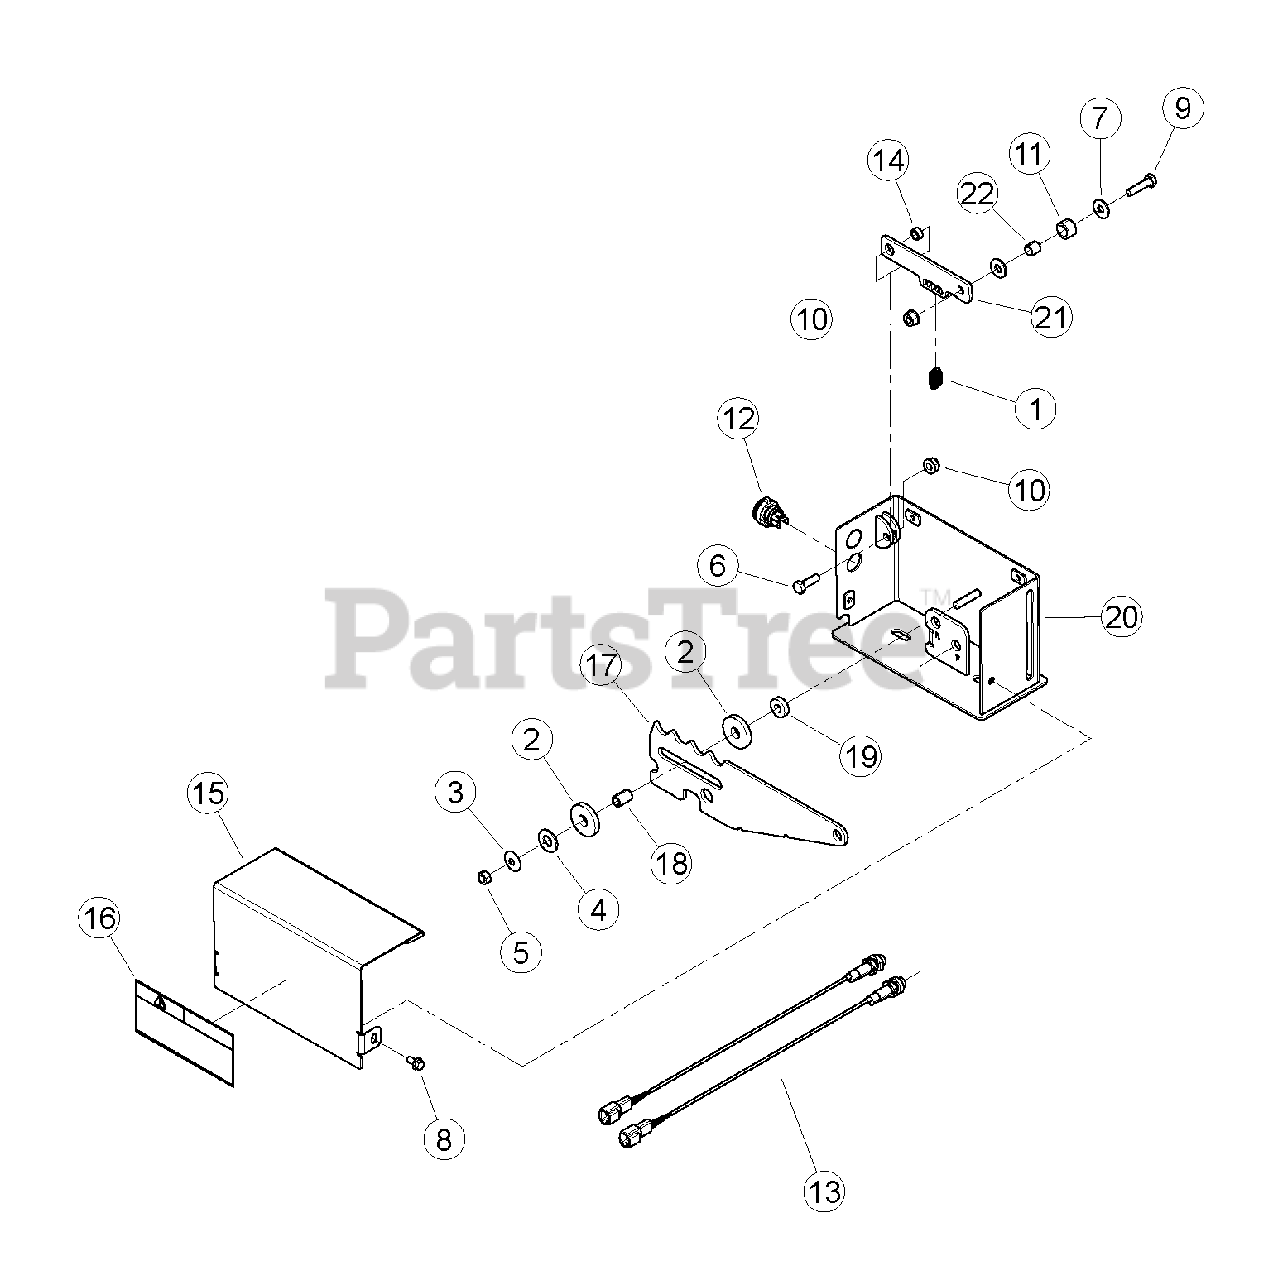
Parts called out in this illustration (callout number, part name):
1	SPRING, CONTROL BAR
2	WASHER, UHMW SPACER .515ID-1.50OD
3	WASHER, SPRING
4	WASHER, 1/2 SAE FLAT ZP
5	NUT, 5/16 CENTERLOCK NC ZP
6	BOLT, 5/16 X 1 HEX GR5 NC ZP
7	WASHER, 5/16 FLAT ZP
8	BOLT, 1/4 X 1/2 SERRATED FLANGE GR5 ZP
9	BOLT, 5/16 X 1-1/4 HEX GR5 NC ZP
10	NUT, 5/16-18 NYLOCK-FLANGE
11	ROLLER, NYLON .75OD X .502ID X .440
12	LIGHT, LED TRI-COLOR
13	SENSOR, M12 PNP PROXIMITY (REPLACEMENT PART)
14	SPACER, IDLER PIVOT
15	ASSEMBLY, CONTROL COVER W/ DECAL
16	DECAL, MULTILINGUAL MANUAL
17	BAR, SWITCH CONTROL
18	SPACER, .50 X .728
19	SPACER, .375" X .25"
20	WELDMENT, SWITCH BOX
21	LINK, DETENT
22	SPACER, 1/2 OD X .35 ID X .47
